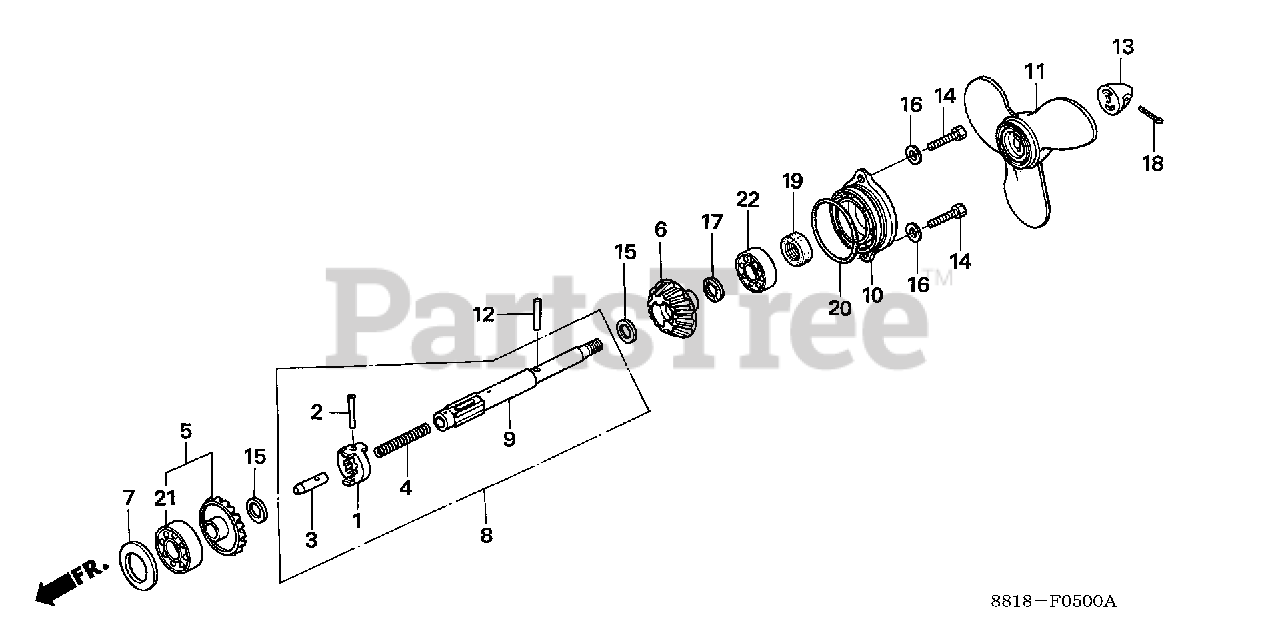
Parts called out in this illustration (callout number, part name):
1	SHIFTER, CLUTCH
2	PIN, SHIFTER (4X35)
3	SLIDER, SHIFT
4	SPRING, SHIFT
5	GEAR, FR. BEVEL
6	GEAR, RR. BEVEL
7	SHIM A, GEAR (0.10MM)
7	SHIM B, GEAR (0.15MM)
8	SHAFT, PROPELLER
9	SHAFT, PROPELLER
10	HOLDER, PROPELLER SHAFT *NH282MU* (OYSTER SILVER METALLIC-U)
11	PROPELLER, THREE-BLADE *NH283* (STIN GRAY)
12	PIN, SHEAR
13	CAP, PROPELLER
14	BOLT, HEX. (6X20)
15	WASHER (17MM)
16	WASHER, PLAIN (6MM)
17	WASHER C, GEAR (2.10MM)
17	WASHER D, GEAR (2.15MM)
18	PIN, SPLIT (3MM)
19	SEAL, WATER (17MM) (NOK)
20	O-RING (66MM)
21	BEARING, RADIAL BALL (6005)
22	BEARING, RADIAL BALL (6203)
